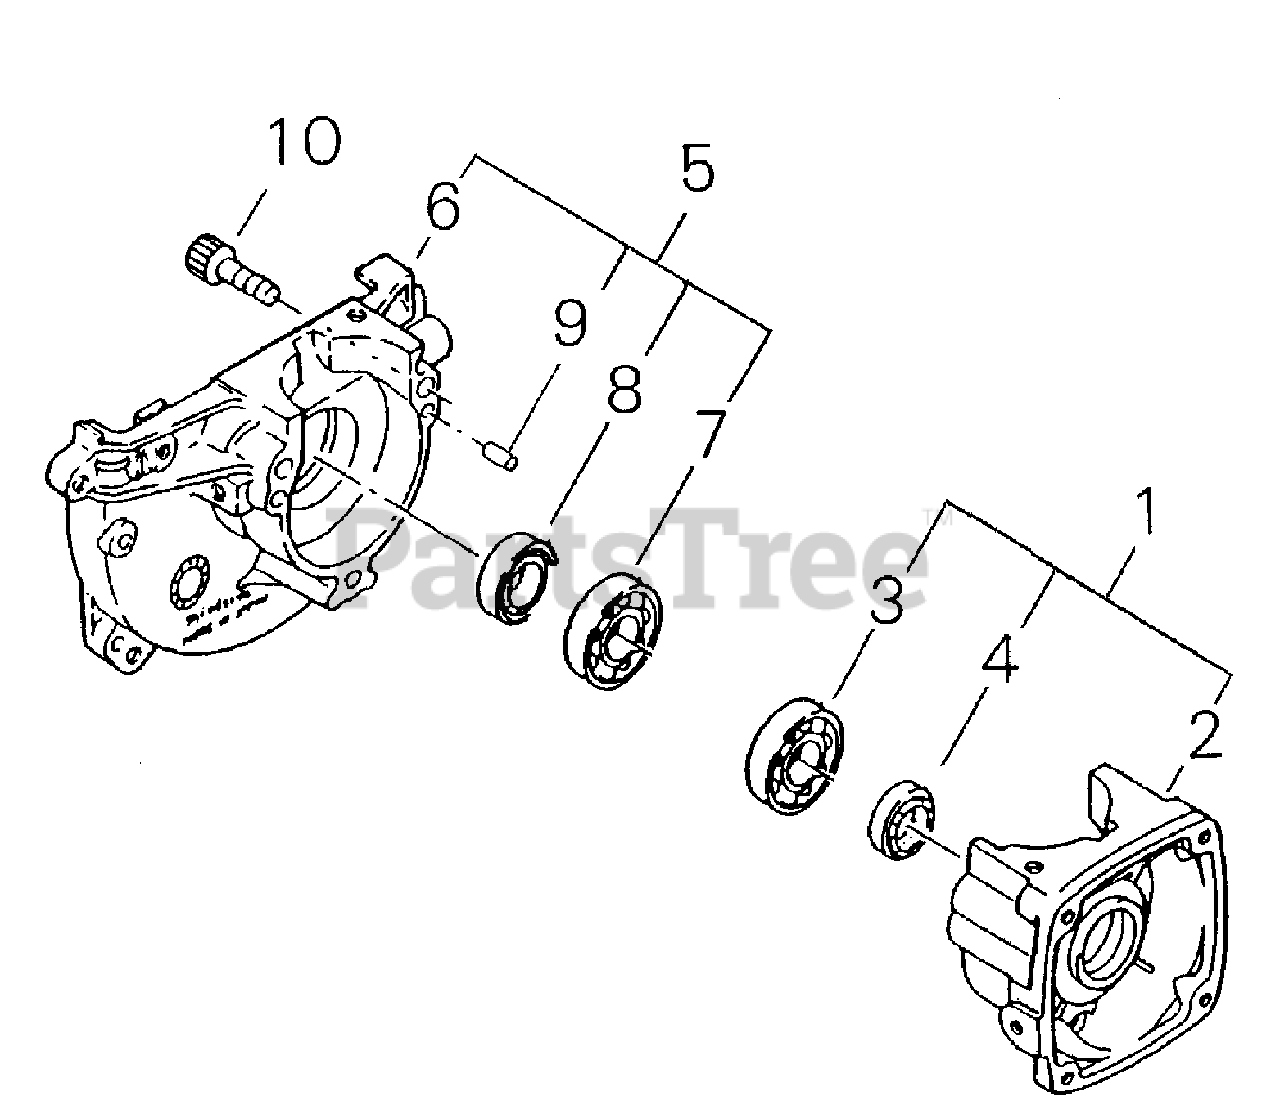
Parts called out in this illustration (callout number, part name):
2	CRANKCASE - REAR
2-1	CRANKCASE ASSY - REAR
3	BEARING, BALL - 6001C3
4	SEAL, OIL
5	CRANKCASE ASSY - FRONT
6	CRANKCASE - FRONT
7	BEARING, BALL - 6001C3
8	SEAL, OIL - 12
9	PIN - LOCATING
10	SCREW - 5X25
